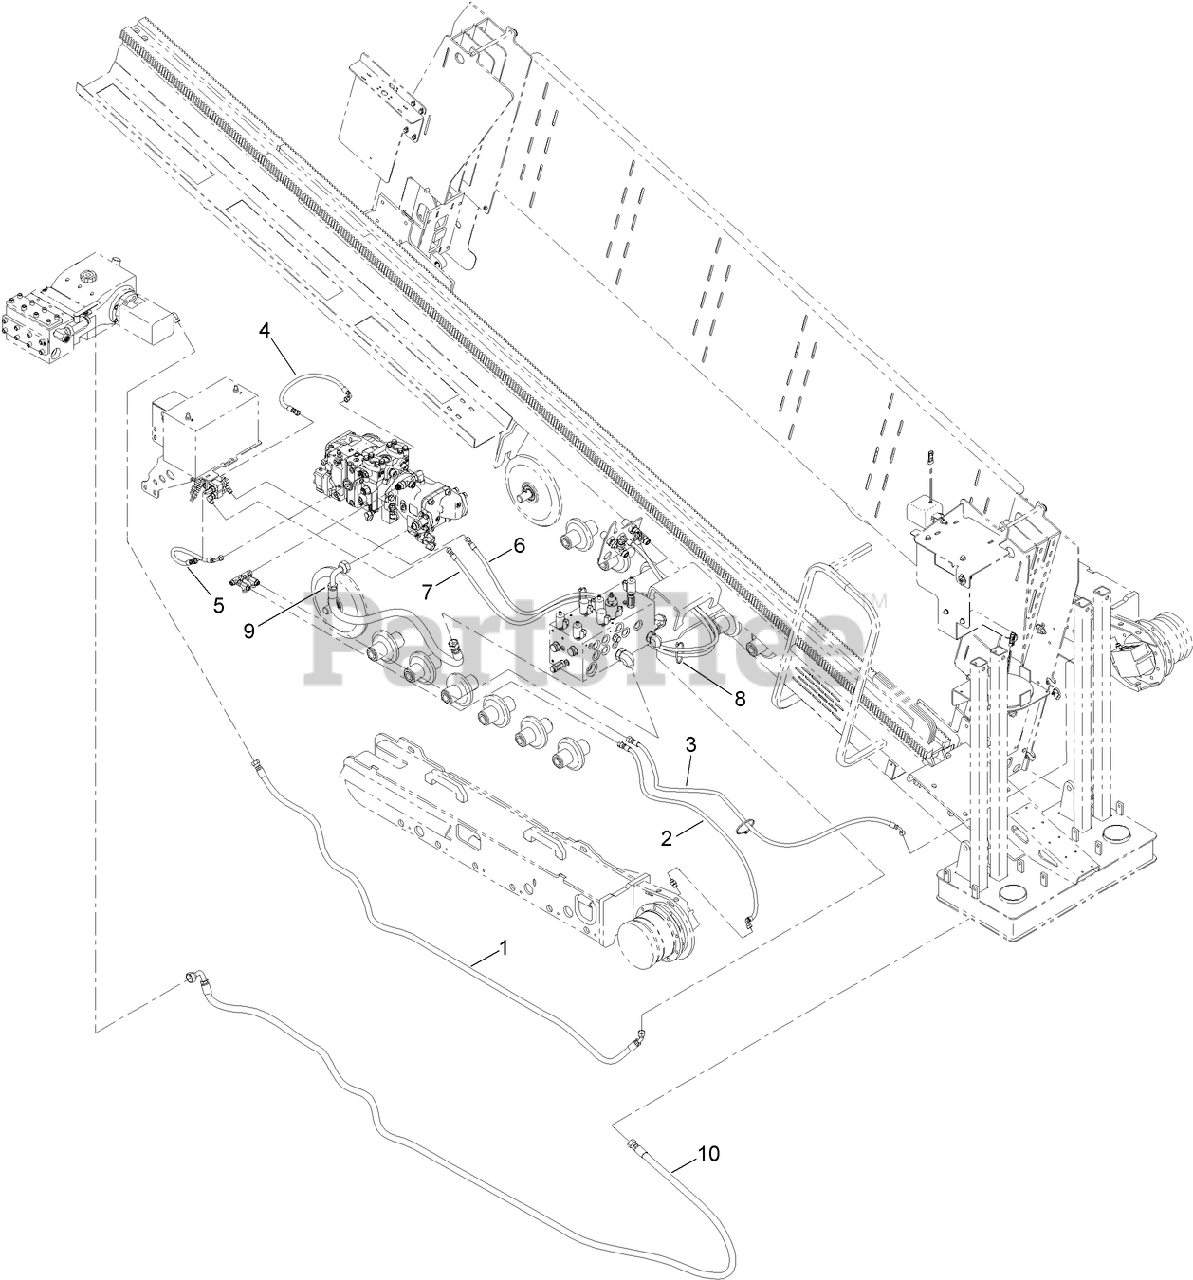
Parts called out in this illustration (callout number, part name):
1	HOSE ASM
2	HOSE ASM
3	HOSE ASM
4	HOSE ASM
5	HOSE ASM
6	HOSE ASM
7	HOSE ASM
8	TIE-CABLE
9	HOSE ASM
10	HOSE ASM
